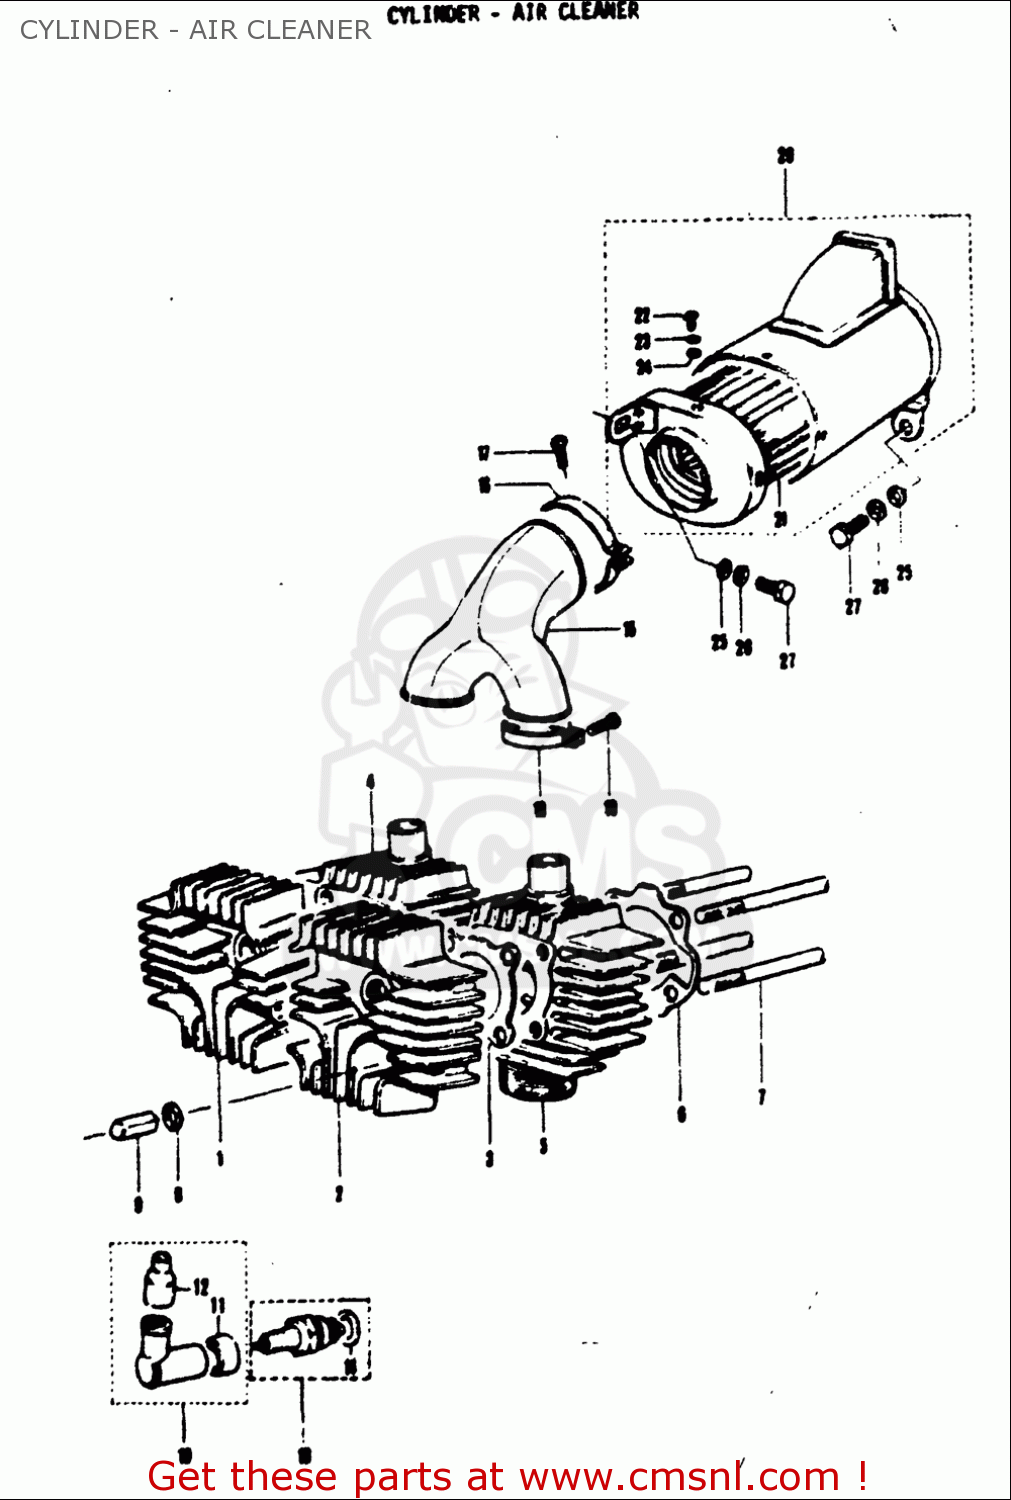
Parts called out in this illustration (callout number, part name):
8	WASHER
9	NUT (6MM)
13	PLUG,SPARK(BP7HS)
14	GASKET(14X19.2X2) (NAS)
16	CLAMP
17	SCREW
18	CLAMP
19	SCREW 4X16
22	WASHER
23	WASHER,LOCK
25	WASHER
26	WASHER,LOCK
